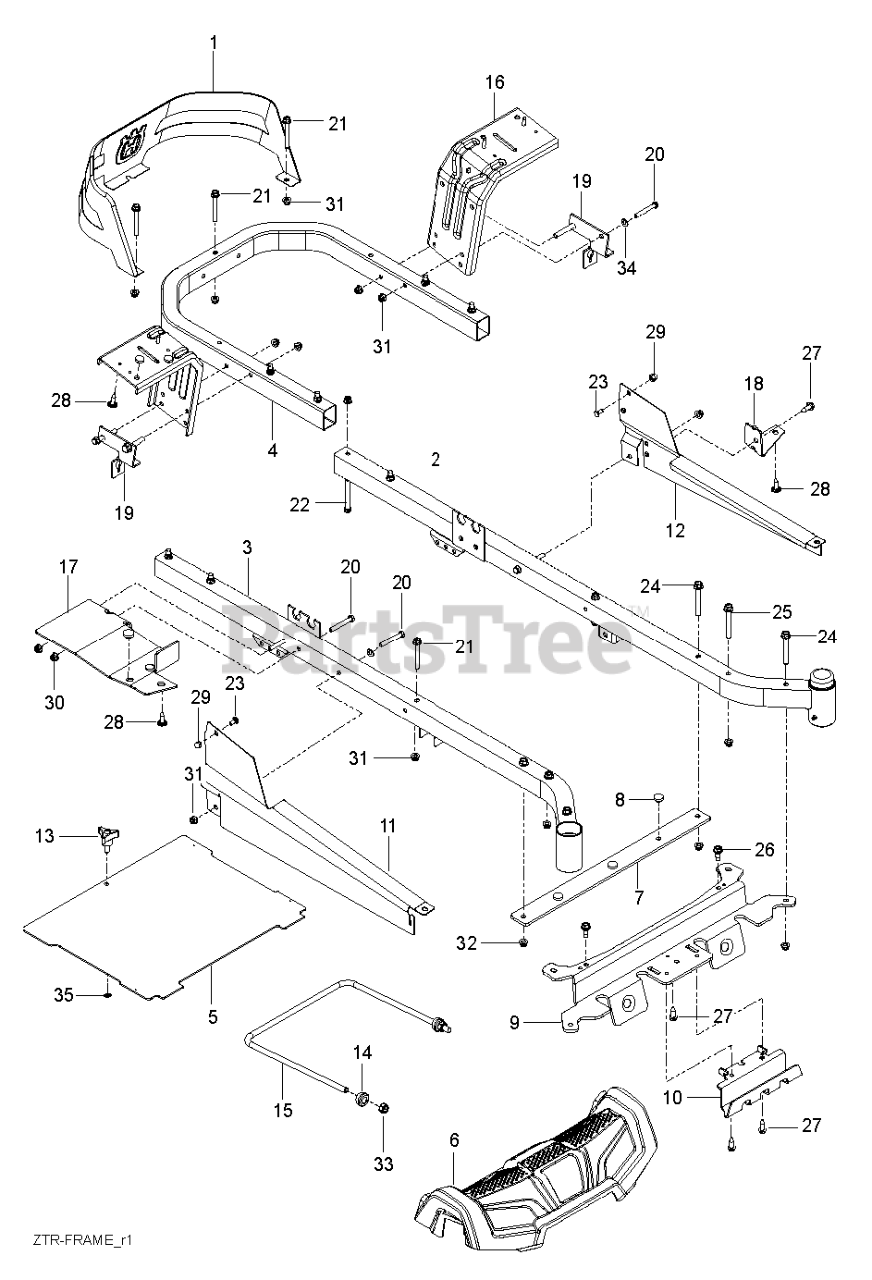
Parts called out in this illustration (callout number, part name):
1	GUARD.ENGINE.HUSQ.RZ.X498
2	FRAME.TUBE.RZ.MAIN.WELD.RH.ORG
3	FRAME.TUBE.RZ.MAIN.WELD.LH.ORG
4	TUBE.PNT.FRAME.RER.HUSQ.23".RZ
5	PLATES
5	PLATE, FOOT W/DECALS RZ
6	FRONT COVER RZ REFRESH
7	FOOTREST.PLATE.SUPPORT.X431
8	GROMMET.BUMPER
9	CROSS.PNT.MEMBER.BLK
10	SKID.PLATE.PNT.RZ.REF.SIVER
11	COVER.RAIL.RH.RZ.X668
12	COVER.RAIL.LH.RZ.X668
13	KNOB W/STUD
14	BUSHING SPHERICAL SUSP. FRONT
15	LINK, FRONT SUSP.
16	FENDER.SUPPORT.PNT.X431
17	SUPPORT.PNT.RH.CONSOLE.FRONT
18	SUPPORT.PNT.LH.CONSOLE.FRONT
19	BRKT ROD.BYPASS.EZT.X431
20	BOLT.FIN HEX 5/16-18UNC X2 1/4
21	BOLT HEX 5/16-18 GR 5
22	BOLT.HEX.FIN.3/8-16 X 3.GR5
23	BOLT.CARRIAGE.5/16-18.7/16
24	HHFS 3/8-16 X 3 GRD 5 ZD
25	BOLT SHOULDER,FLANGED,3/8-16X3
26	BOLT.5/16-18.THRD.ROLL.SHOULDR
27	BOLT.5/16HEX.WHS.HD
28	SCREW.#10 X 0.750.BOS
29	NUT ACORN,FLANGED,5/16-18
30	NUT LOCK HEX FLANGE 5/16-18
31	5/16-18 NYLOC FLANGE NUT
32	NUT 3/8-16 HEX FLG NYLOC ZD
33	7/16-14 HEX NUT W/NYL RING ZD
34	WASHER
35	WASHER 5/16"
